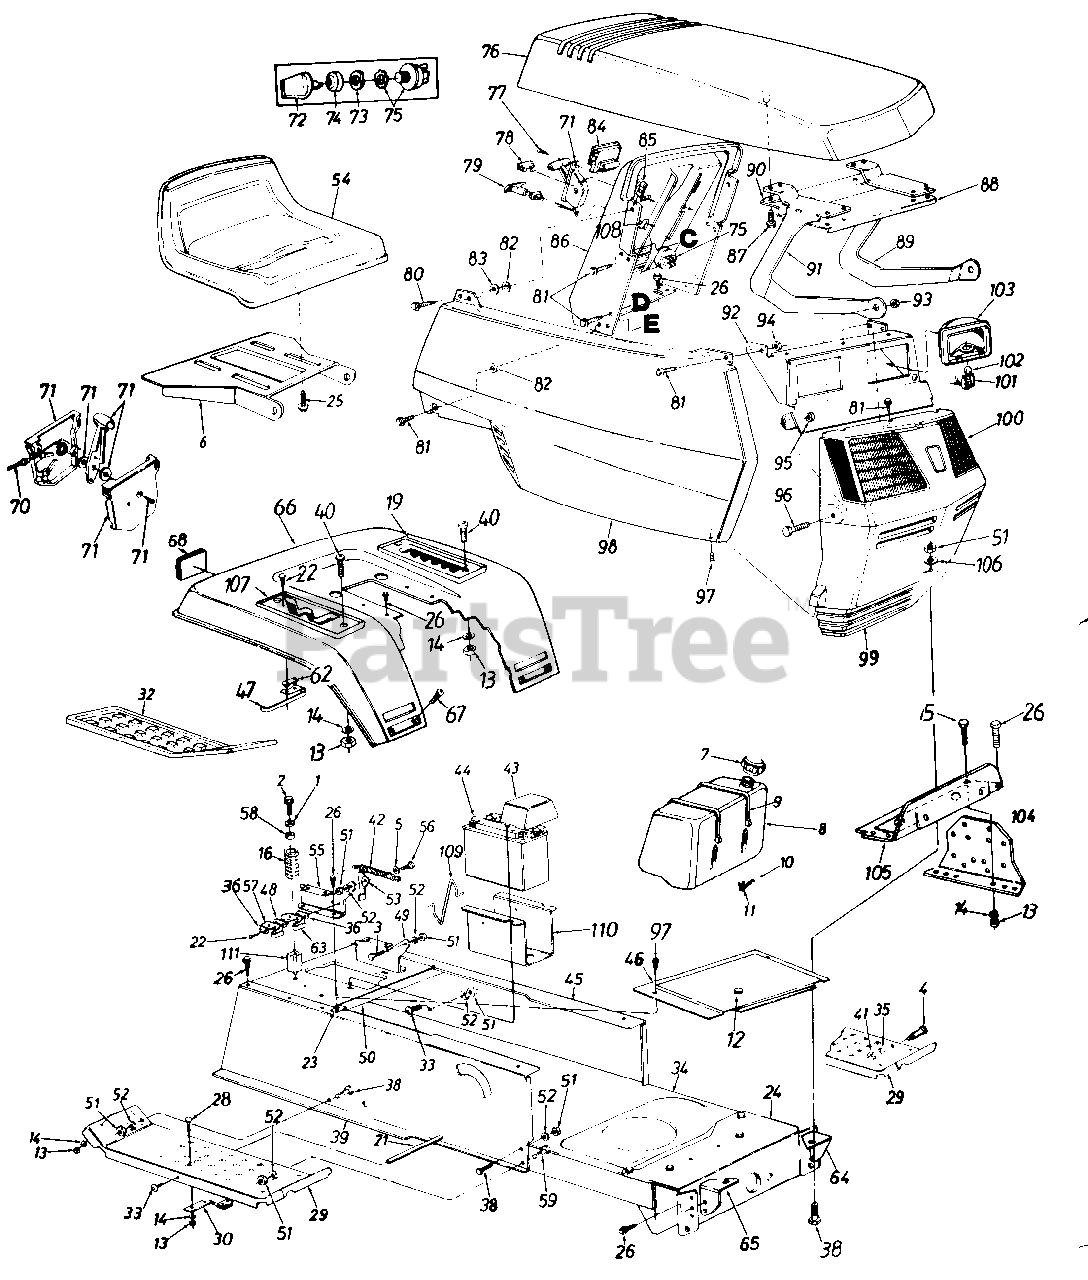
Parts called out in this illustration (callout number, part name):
1	Fl-Wash. .344" I.D. x .875"
2	Hex Wash. Hd. Tap Scr. 5/16-18 x 3.25" Lg.
3	Shld. Bolt .437" Dia. x .162
4	Shld. Bolt .50" Dia. x .84"
5	Spr-Wash. .445" I.D. x .75
6	Seat Pivot Bracket
7	Fuel Cap
8	Fuel Tank
9	Tie Strap
10	Fuel Line
11	Hose Clamp
12	Snap Bushing
13	Hex Nut 1/4-20 Thd.
14	L-Wash. 1/4" I.D.
15	Hex Bolt 1/4-20 x .62" Lg.
16	Compression Spring
19	7-Speed Index Brkt.
21	Running Board Rod
22	Hex Wash. Hd. AB-Tap Scr. #8 x .50" Lg.
23	Speed Nut #10Z
24	Front Pivot Brkt.
25	Hex Tap Scr. 3/8-16 x .75"
26	Hex Wash. Hd. AB-Tap Scr. 5/16 x .75" Lg.
28	Carriage Bolt 1/4-20 x .62"
29	Running Board
30	Blade Brake Ass'y.
32	Rubber Foot Pad L.H.
33	Truss Mach. Scr. 5/16-18 x .75" Lg.
34	Lower Frame
35	L-Wash. 3/8" I.D.
36	Insulator Plate
38	Hex Bolt 5/16-18 x .75" Lg.
39	Upper Frame R.H.
40	Truss Mach. Scr. 1/4-20 x .75' Lg.
41	Hex Nut 3/8-16 Thd.
42	Extension Spring 5.31" Lg.
43	Battery Cover
44	12-V Battery
45	Upper Frame L.H.
46	Shift Cover
47	Reverse Safety Switch
48	Insulator Boss Plate
52	L-Wash. 5/16" I.D.
53	Seat Lift Brkt.
54	Seat
56	Shld. Bolt .437" Dia. x .268"
57	Spring Switch
58	Bushing
59	Hex Wash. TT-Tap Scr. 5/16-18 x 7/8" Lg.
62	Insulator Nut Plate
63	Safety Switch (Seat)
64	Grille Mount Brkt. L.H.
65	Grille Mount Brkt. R.H.
66	Fender
67	Carriage Bolt 1/4-20 x .62" Lg.
68	Reflector
70	Throttle Wire 26" Lg.
71	Throttle Control Box Ass'y.
72	Ignition Key
73	Ignition Switch Nut
74	Ignition Switch Cap
75	Ignition Switch
78	Light Switch
79	Choke Control 29" Lg.
80	Hex Wash. Hd. Tap Scr. 1/4 x.75" Lg.
81	Hex Tap Scr. 1/4-20 x .5" Lg.
82	Push Nut Fastener
83	Fl-Wash. .27" I.D. x .948"
84	Ammeter
85	Speed Nut 1/4-20 Thd.
86	Dash Panel
87	Hex Wash. Hd. B-Tap Scr. 1/4 x .62" Lg.
88	Hood Reinforcement
89	Hood Hinge L.H.
94	Hex L-Nut 1/4-20 Thd.
95	Hex Jam Nut 5/16-18 Thd.
96	Hex Bolt 5/16-18 x 7/8" Lg.
97	Truss Mach. B-Tap Scr. #10 x .5" Lg.
98	Side Cover R.H.
101	Twist Lock Lamp Socket
102	Lamp
103	Headlight Housing
106	Fl-Wash. .34" I.D. x .68"
107	Forward/Reverse Index Brkt.
108	Choke Retainer
109	Battery Tray Clip
110	Battery Tray
111	Spring Spacer
